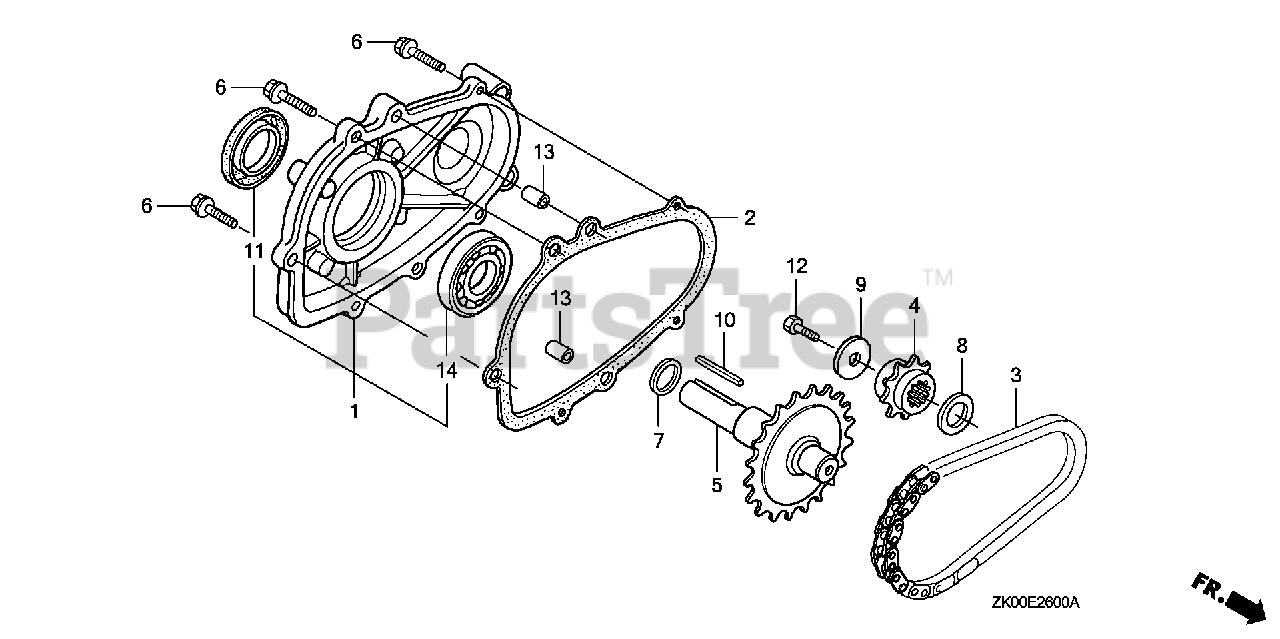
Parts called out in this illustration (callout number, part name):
1	COVER ASSY., CHAIN CASE
2	GASKET, CHAIN CASE COVER
3	CHAIN, P.T.O. DRIVE (DID317FM2-34LE)
4	SPROCKET, DRIVE (13T)
5	SHAFT, P.T.O. (26T)
6	BOLT, FLANGE (6X28) (CT200)
7	SPRING, THRUST
8	SPACER (20MM)
9	WASHER (8MM)
10	KEY (5X5X33) (YELLOW)
11	OIL SEAL (25X41X6) (NOK)
12	BOLT, HEX. (8X25)
13	PIN, DOWEL (8X14)
14	BEARING, RADIAL BALL (6205)
